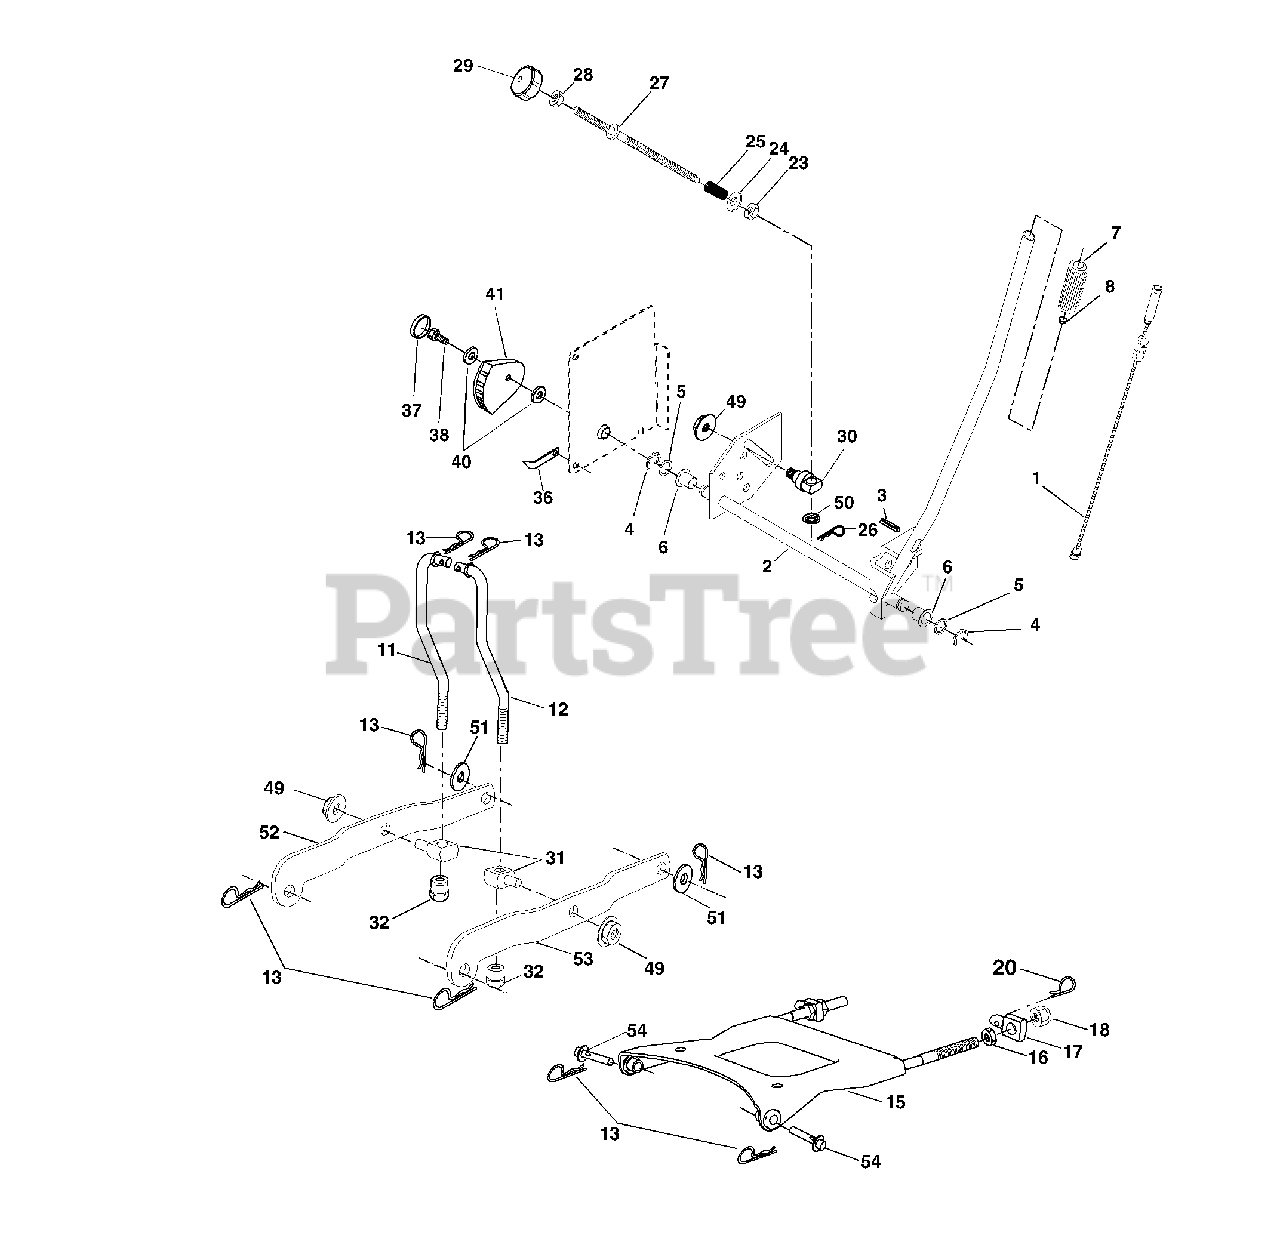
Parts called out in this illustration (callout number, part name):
1	Wire Asm Inner/Sprg W/plunger
2	Shaft Asm Lift RH w/Inf
3	Pin Groove
4	E Ring #5133-62
5	Washer 21/32 X 1 X 21 Ga
6	Bearing Nylon Blk 629 Id
7	Grip Handle
8	Button Plunger
11	Link Lift LH
12	Link Lift RH
13	Retainer Spring
16	Nut Jam Hex 1/2-13 Unc
17	Trunnion Front Susp.
18	Nut Lock w/Wsh 1/2-13unc
20	Retainer Spring
23	Nut Special
24	Washer 13/32 X 5/8 X 16 Ga
25	Spring
26	Retainer Clip
27	Rod Adj Lift
28	Nut Hex Jam 3/8-16 Unc
29	Knob Inf 3/8-16 Unc Blk W/sym
30	Trunnion Infin Height
31	Trunnion Susp. Arm
32	Nut Lift Link 7/16-20
36	Pointer Height Indicator
37	Plug Hole Blk 1.485/1.515 Dia.
38	Screw 5/16-18 x 1
40	Washer 11/32 x 1-1/2 10 Ga.
41	Indicator Height STLT
49	Nut Hex Flange Lock
50	Nut PUsh Phos & Oil
51	Washer 17/32 x 7/8 x 16 Ga.
52	Arm Susp. Rear LH
53	Arm Susp. Rear RH
54	Pin
